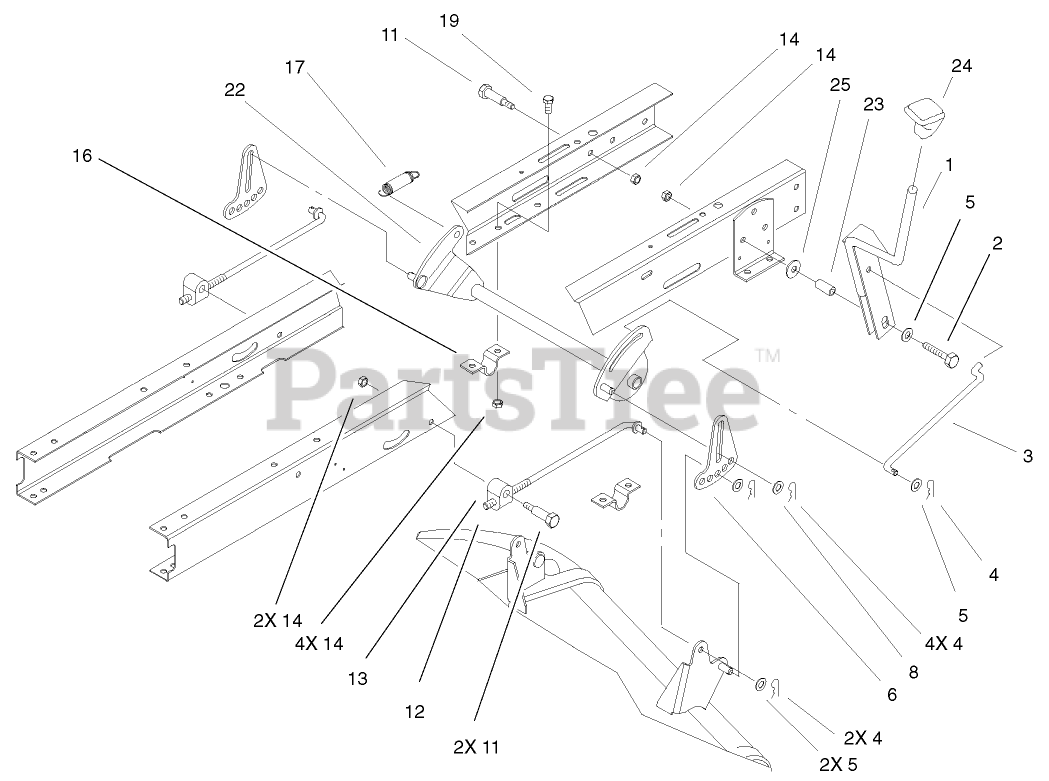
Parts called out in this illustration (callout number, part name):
2	SCREW-HH
3	LINK-HOC
5	WASHER-FLAT
6	LINK-ADJUSTING, HOC
8	WASHER-HARDENED
11	SCREW-SHOULDER, HH
12	ROD-HANGER, REAR
13	TRUNNION-HOC
14	NUT-LOCK, NI
16	CLAMP-PIVOT, HOC
17	SPRING-EXTENSION
19	SCREW-HH
22	PIVOT ASM
23	SPACER
24	KNOB-SHIFT
25	WASHER-PIVOT
